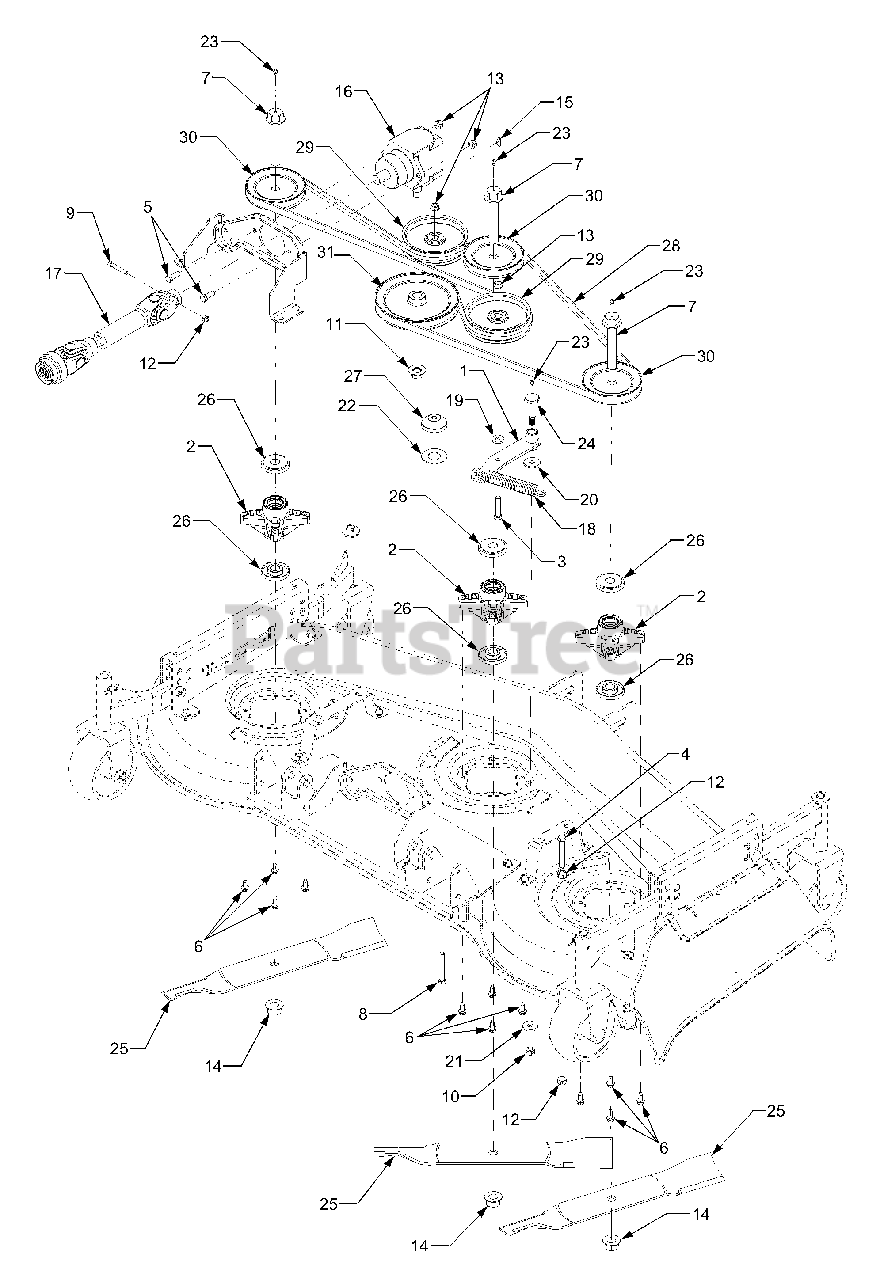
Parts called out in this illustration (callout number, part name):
1	Bracket, Idler
2	Assembly, Spindle
3	Screw, Hex Cap 3/8-16 x 1.75 GR5
4	Screw, Hex Cap 5/16-18 x 2.25 GR5
5	Screw, Hex Cap 3/8-16 x 1.0 GR5
6	Screw, Hex Wash Hd Tapp 5/16-18 x .75
7	Bolt, Spindle, 3/4-16 x 4.25
8	Screw, Hex Cap 3/8-16 x 2.75 GR8
9	Screw, Sock. Hd. 5/16-18 x 1.75
10	Nut, Hex Lock, 7/16-14
11	Nut , Hex Flanged 5/8-18
12	Nut, Hex Nylon Lock 5/16-18
13	Nut, Flange Lock 3/8-16
14	Nut, Hex Flange, 3/4-16
15	Key, Hi-Pro
16	Drive, Right Angle
17	Shaft, Drive
18	Spring, Extension 6.14" Lg.
19	Washer, Flat .385 x 1.0 x .135
20	Washer, Flat, .45 x 1.38
21	Washer, Flat, .45 x 1.25 x .164
22	Washer, Flat 1.01 x 2.0 x .065
23	Fitting, Lube
24	Bolt, Shoulder .68" Dia. x 1.59
25	Blade, High Lift 20.5" Lg.
26	Spacer, Deck Spindle
27	Spacer, Idler
28	Belt, "V" 133" Lg.
29	Pulley, Flat Idler
30	Pulley, "V"
31	Pulley, Drive
